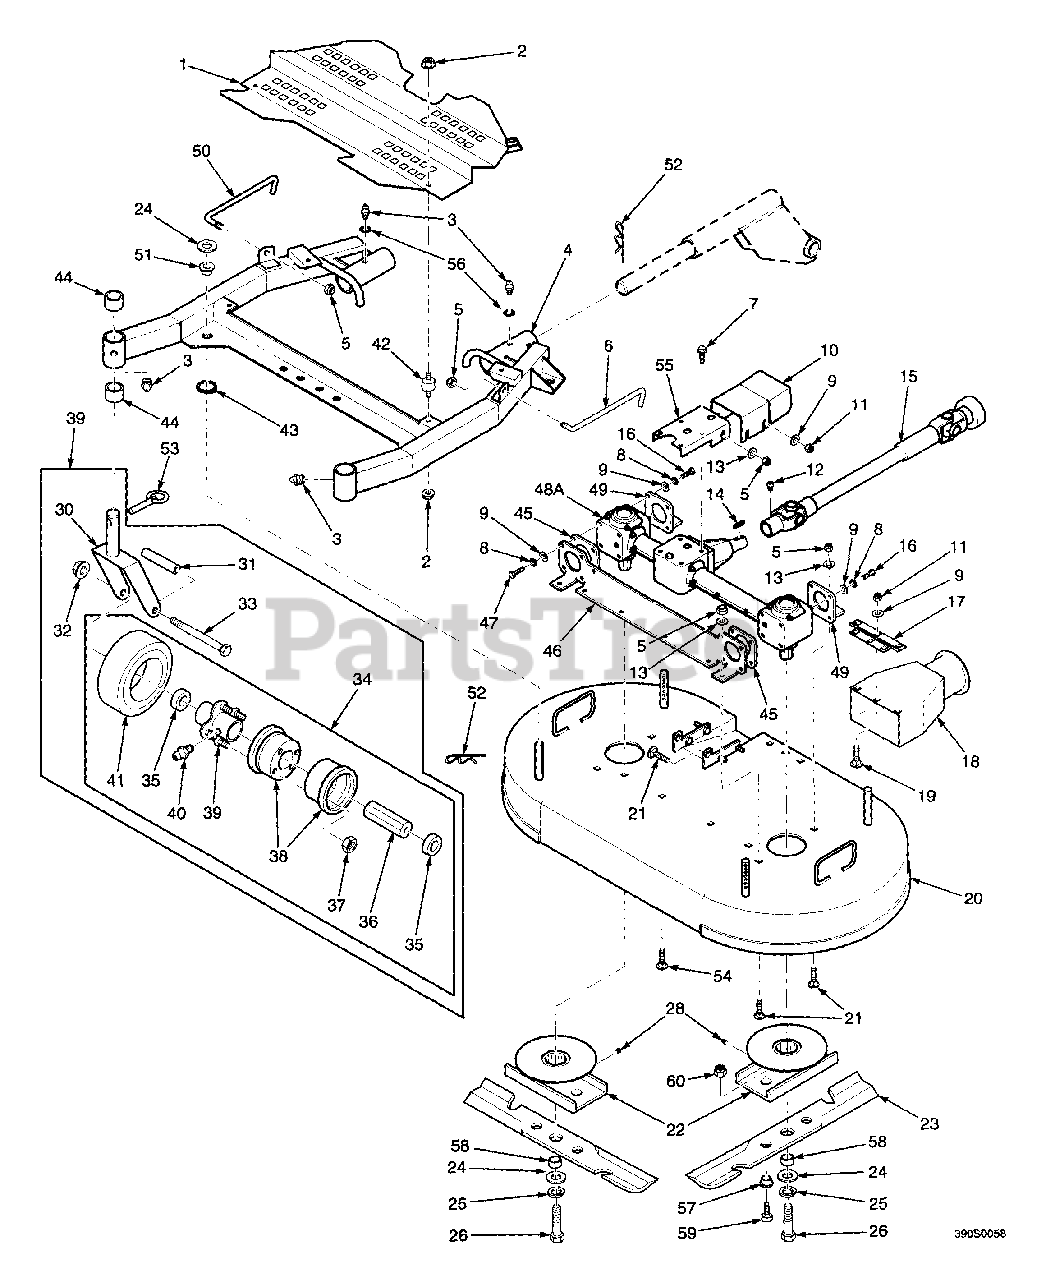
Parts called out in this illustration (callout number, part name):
1	Foot Plate
2	Serr. Fl. Hex Nut, 5/16-18
3	Grease Fitting
4	Frame, Cutter Deck Support
5	Hex Locknut, Elastic Stop, 3/8-16
6	Rod, Deck Prop - L.H.
7	Serr. Fl. Hex Head CPSCRW, 5/16-18 x 3/4"
8	Lockwasher, 5/16"
9	Flatwasher, 5/16 (.375 x .875 x .083)
10	Guard, U-Joint
11	Hex Locknut, Elastic Stop, 5/16"
12	Setscrew, Torx Socket, 3/8-16 x 3/8
13	Flatwasher, 3/8 (.391 x .938 x .105)
14	Key, 1/4 x 1/4 x 1.00"
15	Drive Shaft
16	Bolt, Hex Head, 5/16-18 x 1.00"
17	Hinge, Discharge Chute
18	Chute, Cutter Deck
19	Carriage Bolt, 5/16-18 x 3/4"
20	Cutter Deck With Decals
21	Carriage Bolt, 3/8-16 x 1.0"
22	Adapter, Blade Drive
23	Blade, Cutter - L.H.
24	Flatwasher, 5/8 (.688 x 1.750 x .134)
25	Lockwasher, 5/8"
26	Bolt, Hex Head, 5/8-11 x 1-3/4"
28	Setscrew, Hex Socket, 5/16-18 x 3/8"
30	Yoke, Caster Wheel
31	Sleeve
32	Hex Locknut, Elastic Stop, 1/2-13
33	Bolt, Hex Head, 1/2-13 x 5-1/2"
34	Caster Wheel Assembly
35	Retainer, Caster Wheel
36	Roller Bearing, Caster Wheel
37	Tapered Hex Nut, 5/16-24
38	Rim Pair, Caster Wheel
39	Hub Assembly with Bolts
40	Grease Fitting
41	Tire
42	Isolator, Rubber
43	Retainer Ring, 1.00"
44	Bushing, Oilite, .877 ID
45	Spacer
46	Mounting Bracket - Front
47	Bolt, Hex Head, 5/16-18 1-1/4"
48A	Gearbox, Left and Right
49	Mounting Bracket - Rear
50	Rod, Deck Prop - R.H.
51	Bushing, Cutter Deck Support
52	Hairpin, Cotter, .177 x 3.25"
53	Quick Pin
54	Carriage Bolt, 3/8-16 x 1-1/4"
55	Bracket, Anti-Rotation
56	Washer, Internal Lock
57	Spacer Shear Bolt
58	Spacer, Cutter Blade
60	Locknut, #8-32 Elastic Stop
